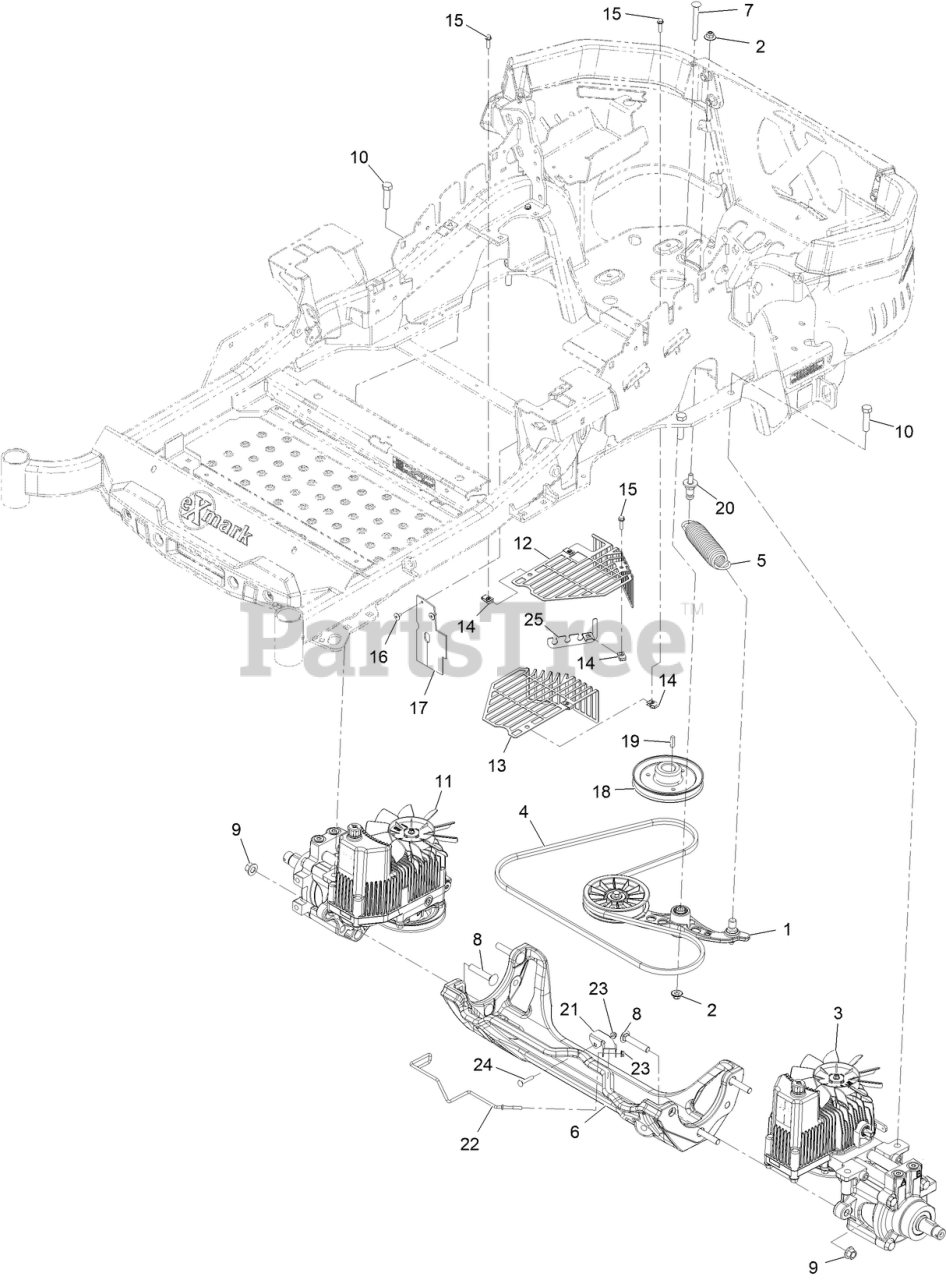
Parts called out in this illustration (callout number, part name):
1	PUMP IDLER ASM
2	Nut-Nyloc 3/8-16 Flg
3	HYDRO-LH
5	SPRING-EXTENSION
6	CRADLE-HYDRO
7	BOLT-SHOULDER, CARRIAGE 3/8-16 X 3 1/2
8	SCREW-CARR
9	Nut-Lock 1/2-13
10	SCREW-HH
11	HYDRO-RH
12	SHROUD-RH HYDRO
13	SHROUD-LH HYDRO
15	SCREW-HHF
16	RIVET-POP
17	DEFLECTOR-AIR FLOW
18	SHEAVE-W/ HUB 5.81
20	Pin-Spring, Anchor
21	Bracket-U
22	Guide-Belt
24	SCREW-CARR
25	Clip-Vent Lines
